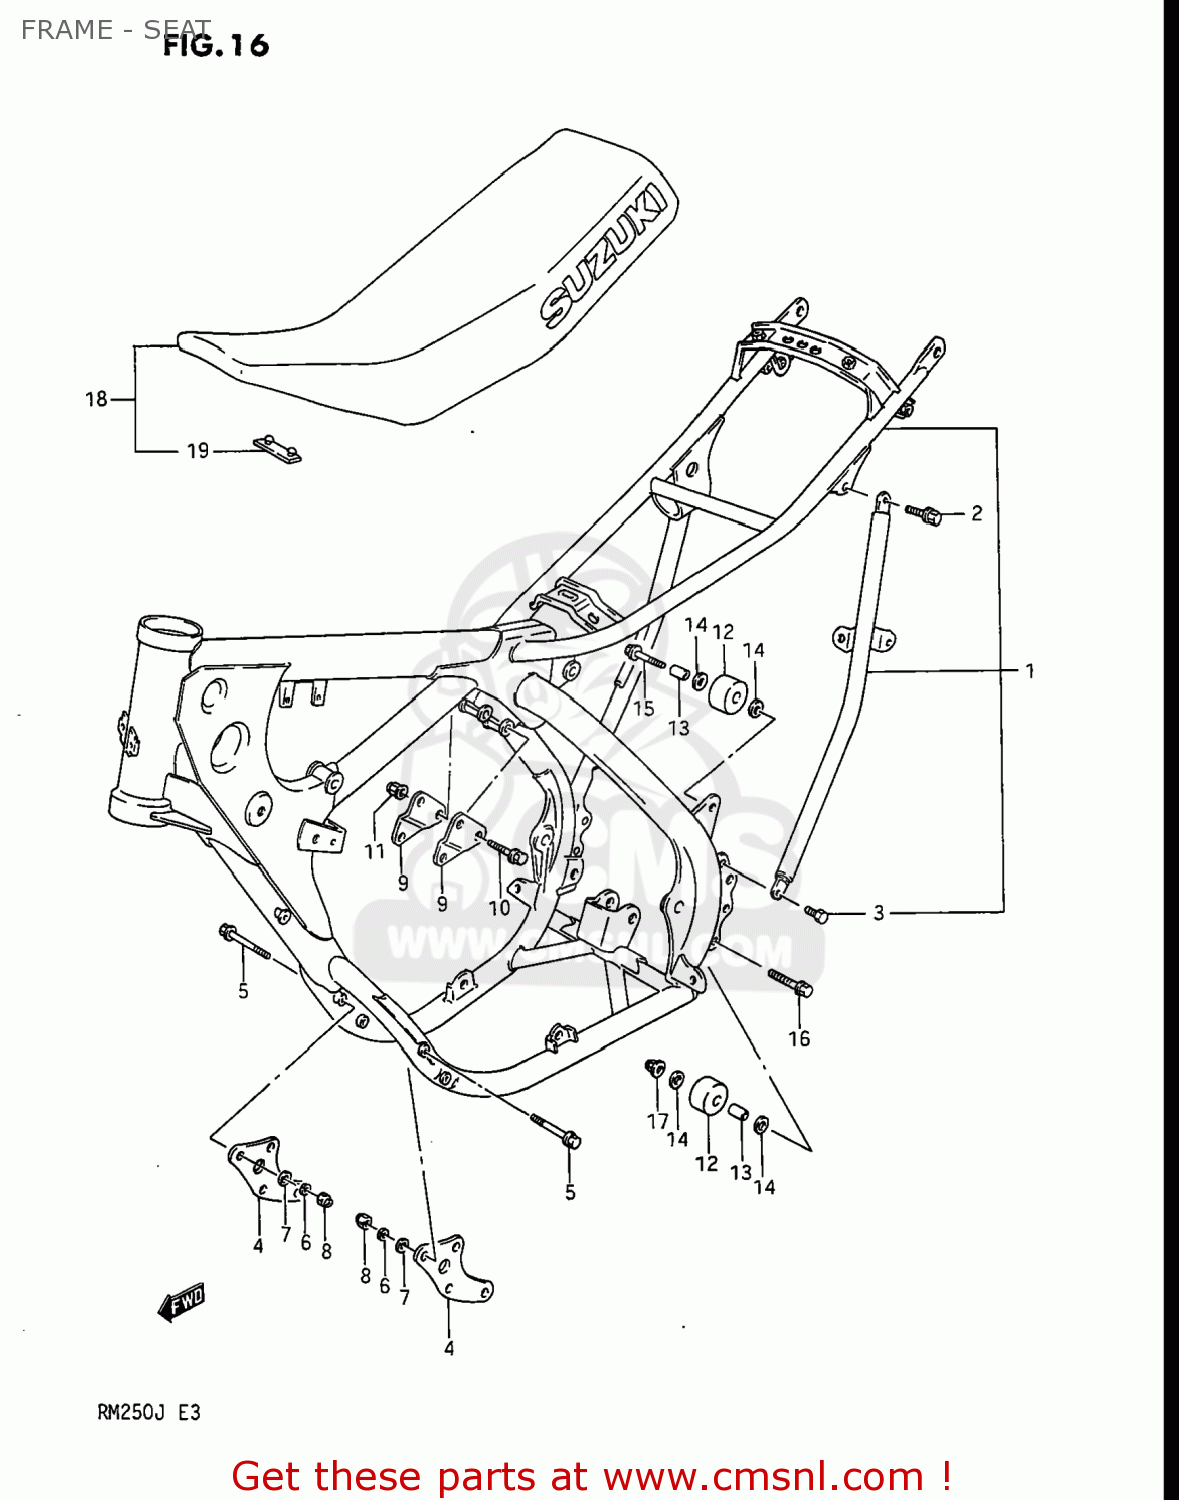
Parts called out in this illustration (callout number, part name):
1	FRAME
2	BOLT
3	BOLT
4	PLATE,ENGINE MOUNTING
5	BOLT 8X55
6	LOCK WASHER
7	WASHER
8	NUT
9	PLATE,ENGINE MOUNTING
10	BOLT 8X45
11	NUT
12	ROLLER,CHAIN CONTROL
13	SPACER (8.6X13.8X28)
14	WASHER
15	BOLT(8X41)
16	BOLT(8X50)
17	NUT
18	SEAT SET
19	CUSHION
